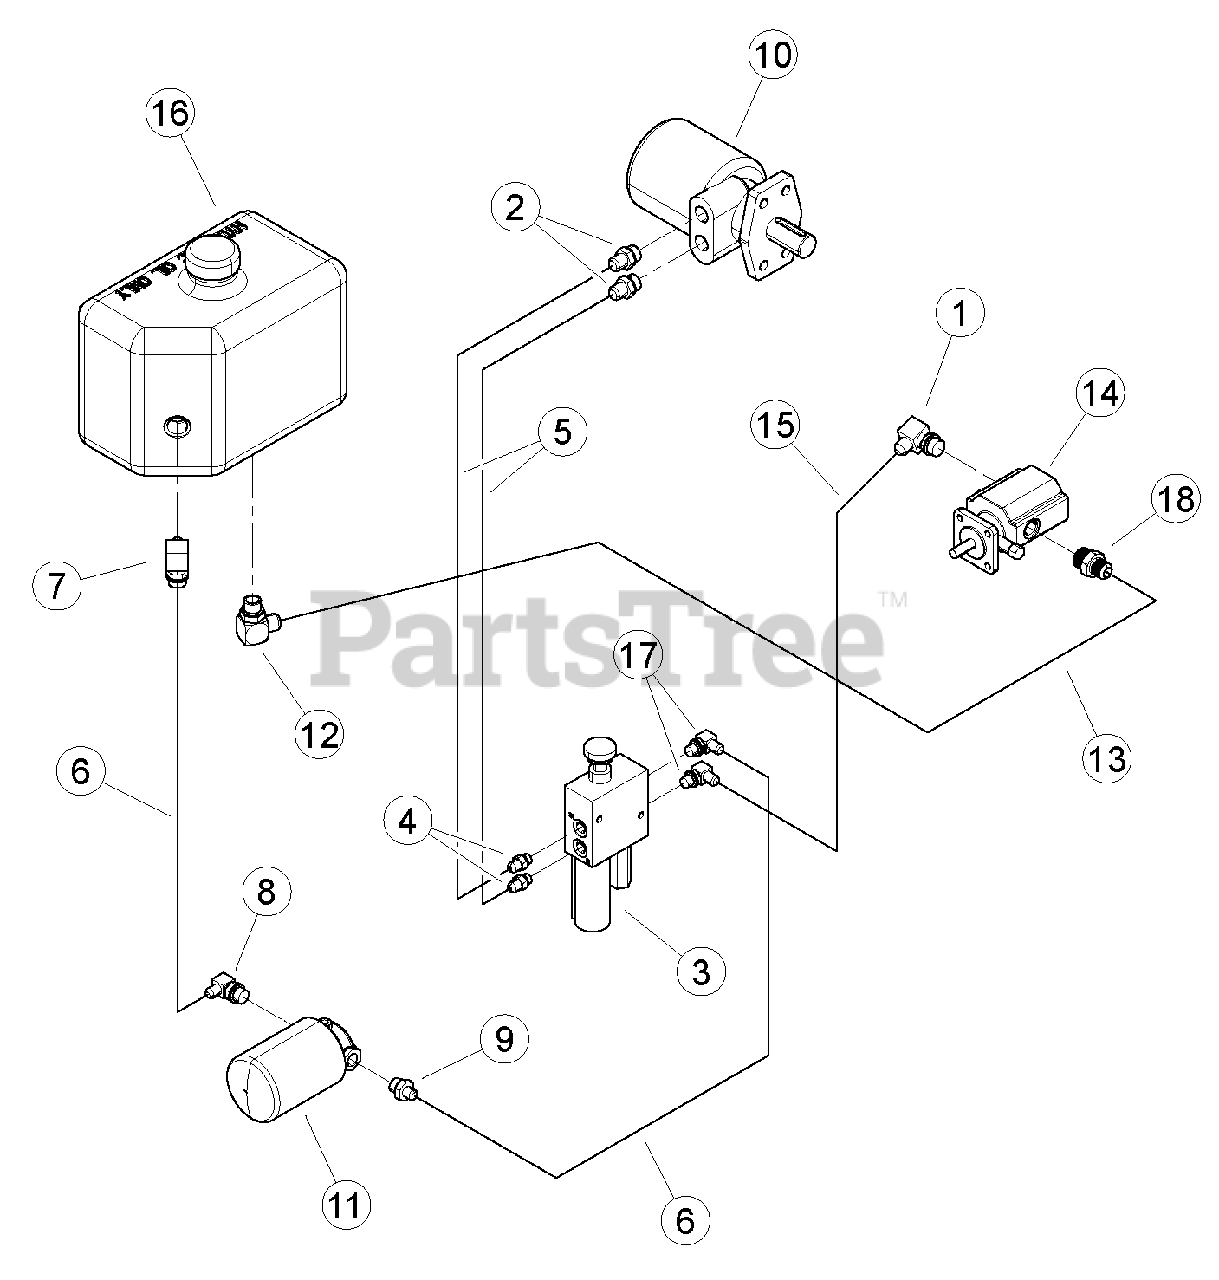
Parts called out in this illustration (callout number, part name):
1	ADAPTER, -10MORING/-8MJIC 90 DEG
2	ADAPTER, -10MORING/-8MJIC
3	VALVE, HYDRAULIC CONTROL
4	ADAPTER, -6MORING/-6MJIC
5	HOSE ASSEMBLY, -8FMJ/-6FMJ X 31
6	HOSE ASSEMBLY, -6FMJ/-6FMJ X 30
7	ADAPTER, -10MORING/-6MJIC 90
8	ADAPTER, -8MORING/-6MJIC 90 DEG
9	ADAPTER, -8MORING/-6MJIC
10	MOTOR, 45 CU IN HYDRAULIC
11	ASSEMBLY, HYDRAULIC FILTER
12	ADAPTER, -10MORING/-10MJIC 90 DEG
13	HOSE ASSEMBLY, -10FMJSW90/-10FMJ X 42
14	PUMP, 2 STAGE CW HI/LO 0.605 DISP.
15	HOSE, -8 FMJ/-6FMJ X 31" HYDRAULIC
16	TANK, HYDRAULIC
17	ADAPTER, -6MORING/-6MJIC 90 DEG
18	ADAPTER, HYDRAULIC PUMP FITTING
